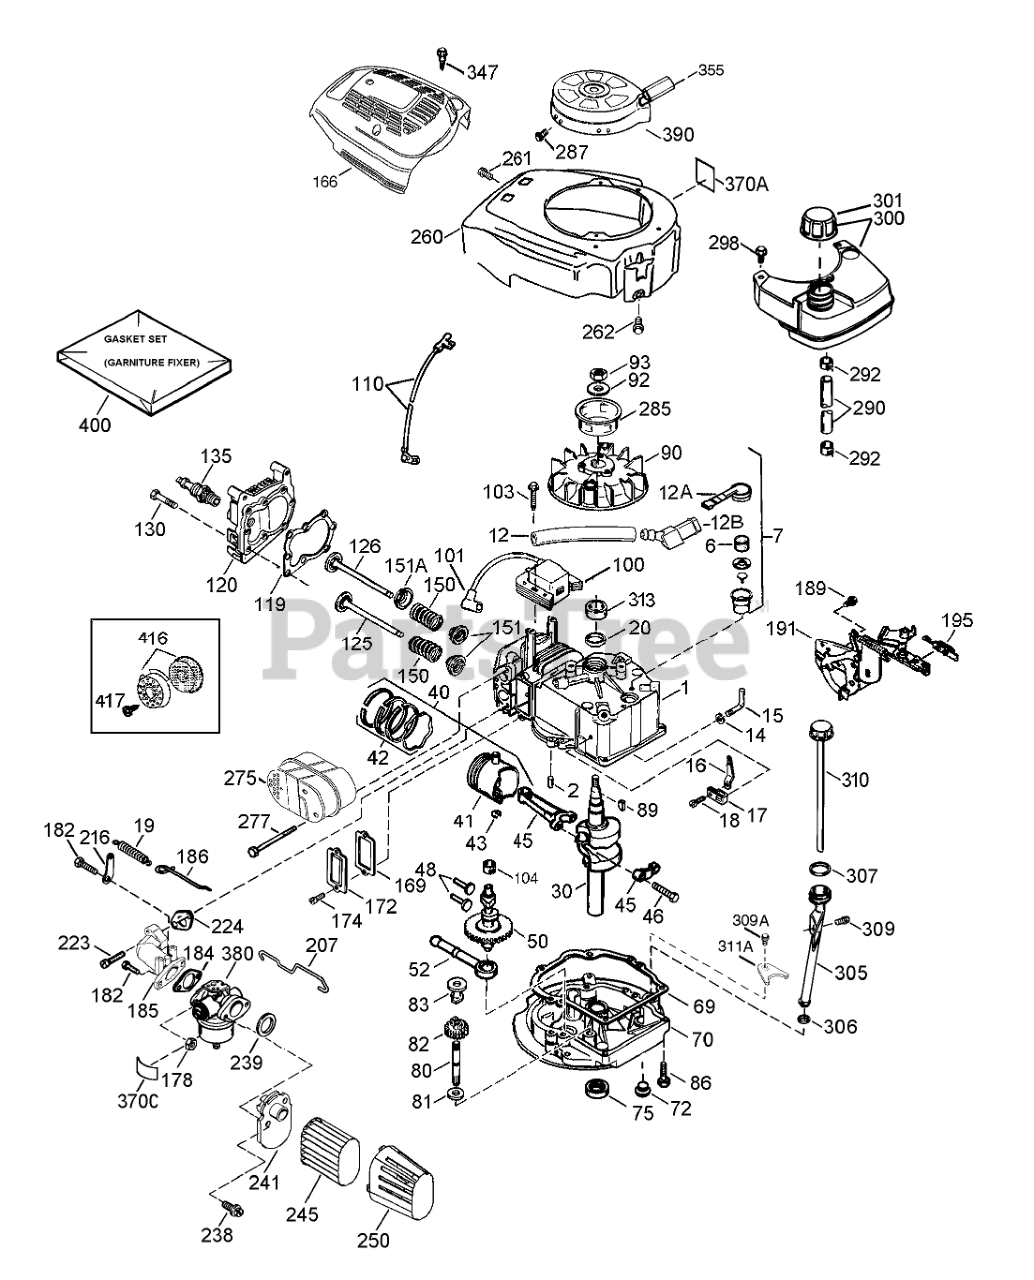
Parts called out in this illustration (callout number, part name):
313	Spacer
347	Screw (10-32 x 27/32)
370	Decal-Warning
370A	Decal-Lubrication
370C	Decal-Primer
380	(Incl. Ref. #184 of Engine Parts List)
390	Rewind Starter ASM
400	Gasket Set (Incl. Items Marked PK in Notes)
416	Spark Arrestor Kit
